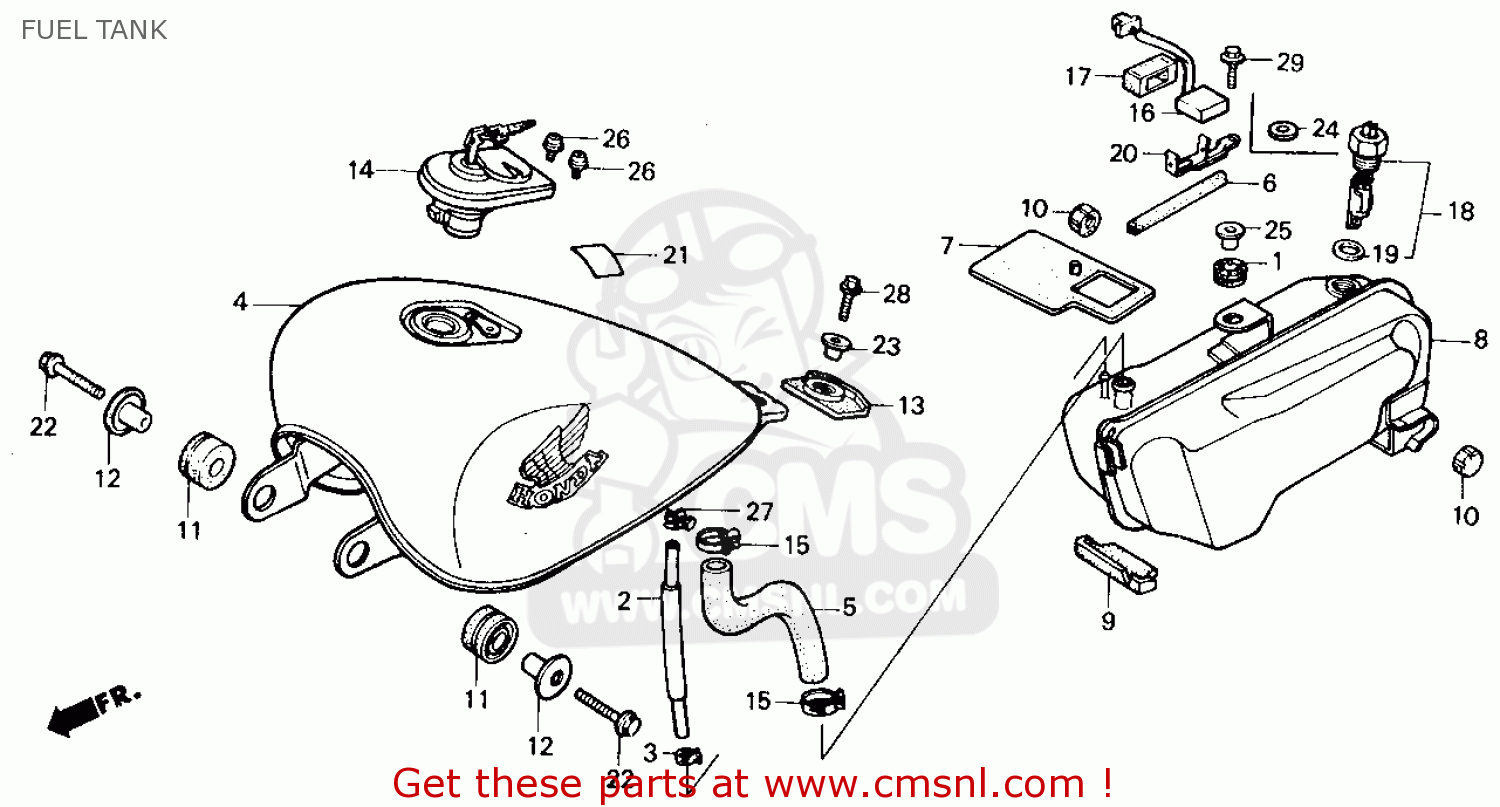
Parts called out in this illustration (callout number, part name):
1	GROM.,OIL COOLER
2	TUBE,FUEL BREATHE
3	CLIP,FUEL HOSE
4	TANK *R-147C-U*
5	TUBE,FUEL JOINT
6	TRIM,FUEL TANK
7	COVER, ELECTRIC
8	TANK COMP.,FUEL S
9	CUSH.,FUEL SUB TA
10	CUSHION,TANK FR.
11	CUSHION TANK FR
12	COLLAR,TANK MOUNT
13	CUSH,FUEL TANK RR
14	CAP COMP.,FUEL FI
15	CLIP B,HOSE.
16	SENSOR
17	SUSPENSION
18	SENSOR,FUEL RESER
19	PKG,FUEL.RESERVE
20	BRACKET
21	MARK DRIVE CAUTION
22	BOLT,FLANGE,8X36
23	COLLAR,FUEL TANK
25	COLLAR,8.8X11
26	SCREW-WASH.,4X8
27	CLIP A12,TUBE
28	BOLT,FLANGE,8X22
29	BOLT,FLANGE 8X22
